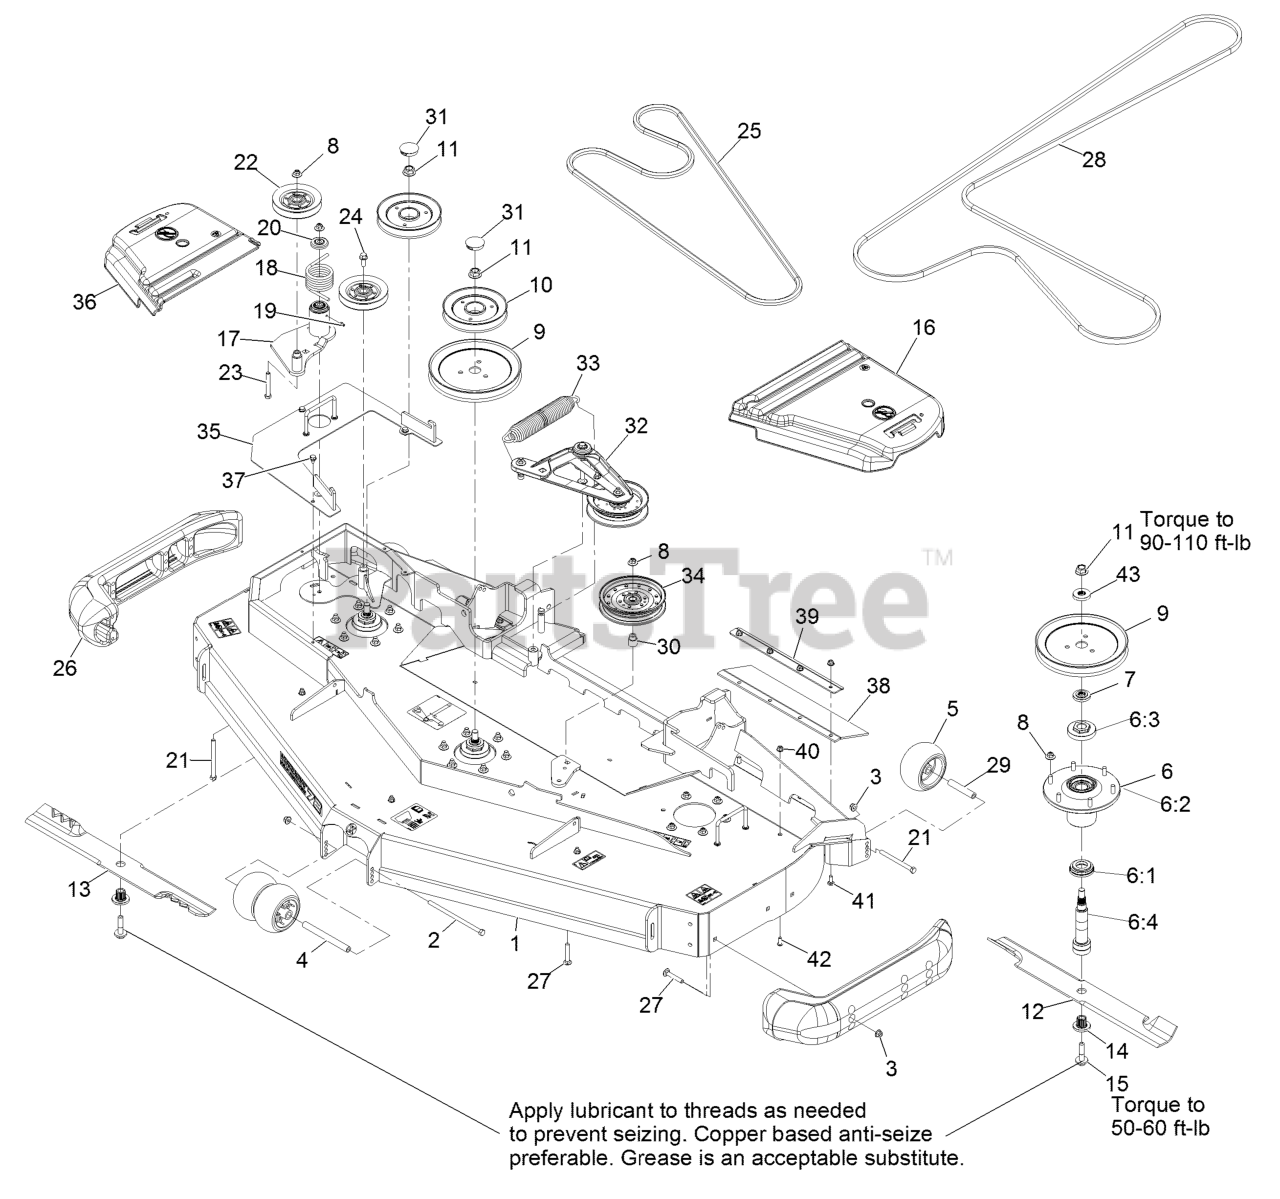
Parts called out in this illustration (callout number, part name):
1	DECK-RD72 NLZ, W/DECALS
2	SCREW-HH
3	NUT-HF, NI
4	SPACER-WHEEL
5	ROLLER-SCALP, ANTI
6	ASM,SPINDLE HOUSING
6:1	GUARD,BOTTOM
6:2	ASM,CUTTER HOUSING
6:3	NUT, SPINDLE 7/8-14
6:4	SPINDLE,DOUBLE SPLINE
7	SPACER,SPLINED STEPPED
8	Nut-Nyloc 3/8-16 Flg
9	SHEAVE,BLADE DRIVE 9.00
10	SHEAVE-RD, REVERSE DRIVE
11	NUT-FLANGE, CENTERLOCK
14	BUSHING,SPLINED
15	SCREW,SEMS 1/2-20 X 2.19
16	COVER-BELT, LH
17	IDLER ASM
18	SPRING-TORSION
19	FITTING-GREASE
20	GUARD-TOP
21	SCREW-HH
23	SCREW-HH
24	SCREW-HHF
26	SKID-BUMPER, DECK
27	Bolt-Carriage 3/8-16 X 2 1/4
28	BELT
29	TUBE-SPANNER
30	BUSHING-IDLER
31	PLUG,BLACK NYLON 1.75
32	DECK IDLER ASM
33	SPRING-EXTENSION
35	COVER-REVERSE DRIVE
36	COVER-BELT, RH
38	GUARD-TIRE
39	SUPPORT-OUTER FLAP
40	NUT-HF, NI
41	SCREW-CARR
42	SCREW-HSBH
43	SPACER,SPLINED
